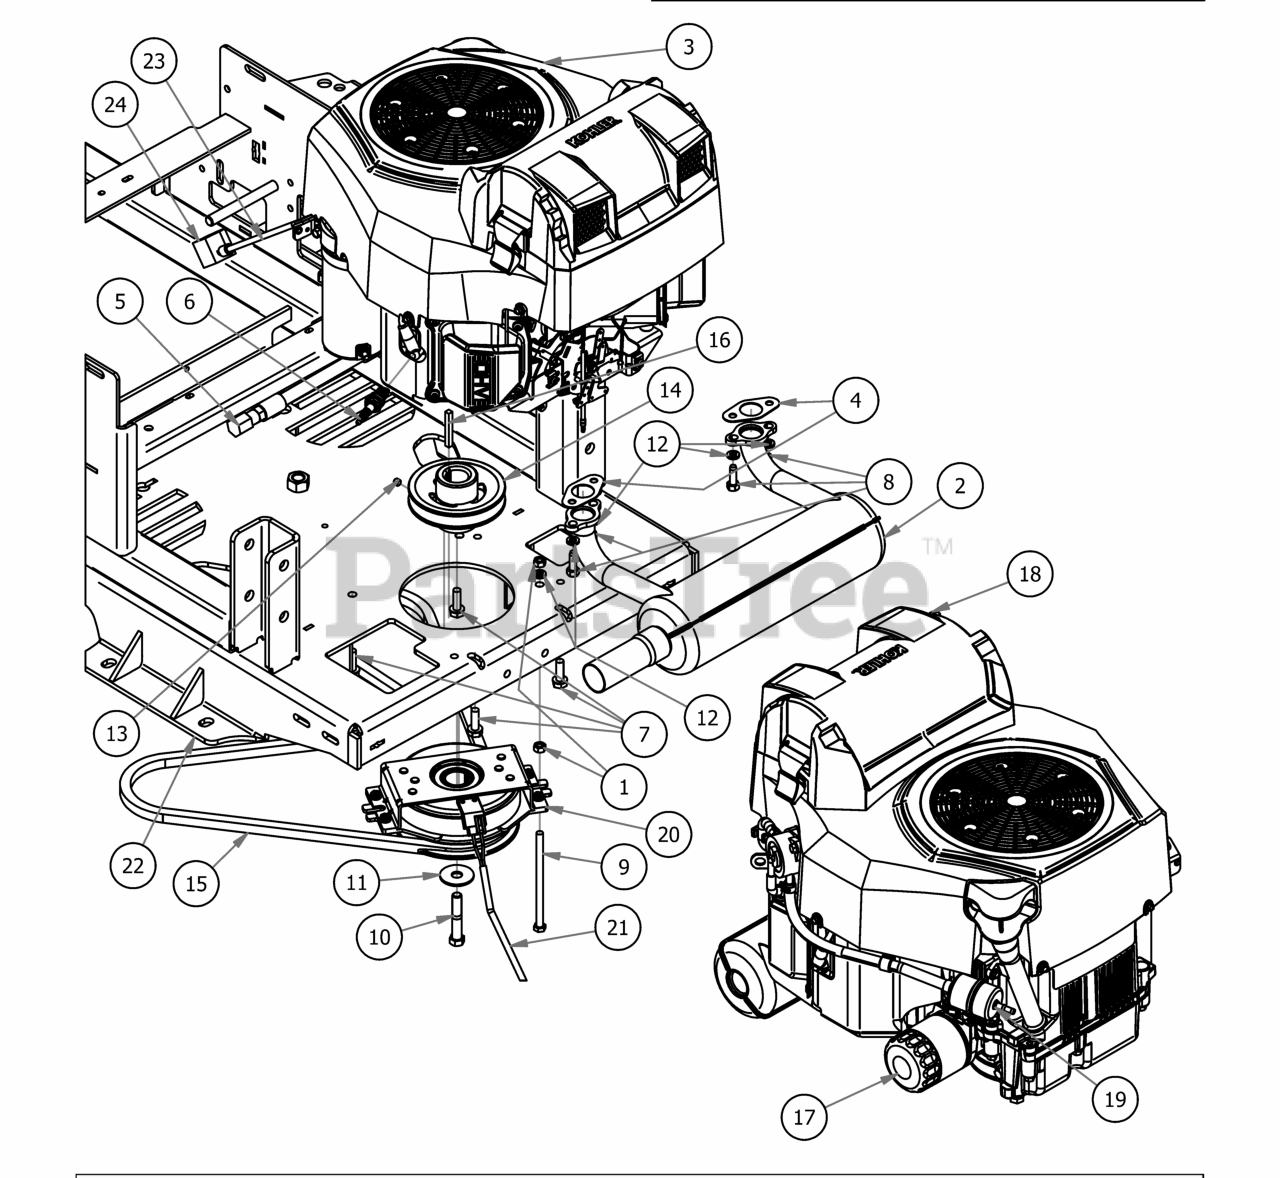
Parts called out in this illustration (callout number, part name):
2	Kohler Muffler
3	Kohler 747cc Engine
4	Exhaust Gasket
5	Oil drain Valve
6	Spark Plug
7	3/8 x 1 1/8 bolt
8	5/16-18 x 1 GR 5 Hex Bolt Zinc
9	5/16-18 x 5-1/2 GR 5 Hex Bolt
10	7/16"-20 x 2.5" Hex Bolt Gr. 8
11	1/2" Belleville Washer
12	5/16" Lock Washer
13	5/16 Set Screw
14	4 3/4 Motor Pulley
15	75.8 Pump Belt
16	1/4 x 2 Square key Stock
17	725 & 747 Kohler Oil Filter
18	725 Kohler air filter
19	Universal Inline Fuel Filter
21	Clutch Pigtail
22	2018 Maverick Frame
23	Ground Cable
24	Black Boot For Ground Cable
